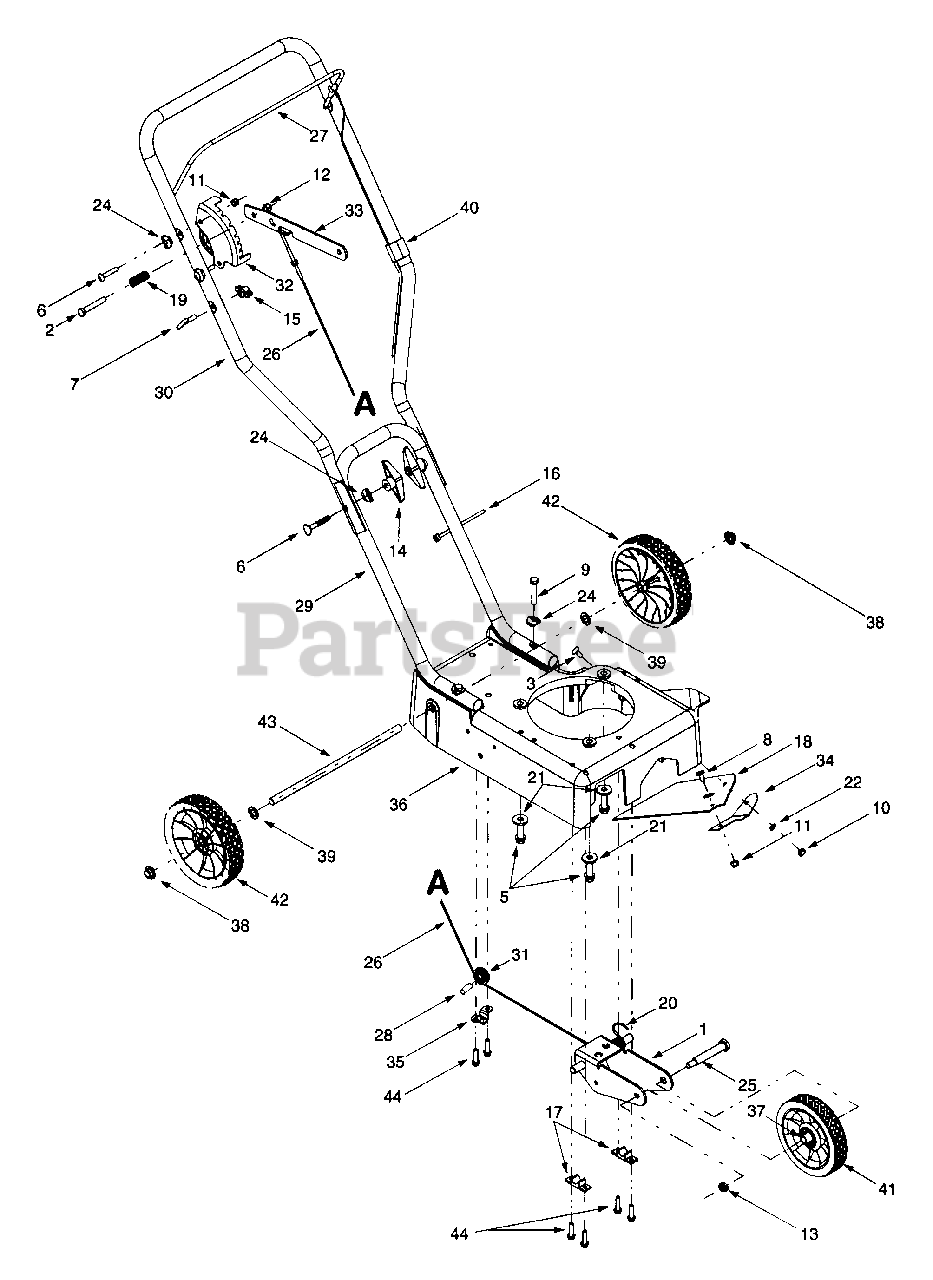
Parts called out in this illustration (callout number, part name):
1	Front Wheel Bracket Assembly
2	Hex Cap Screw, 5/16-18 x 2.0
3	Carriage Screw, 1/4-20 x.625
5	Sems Screw, 3/8-16 x 1.5
6	Carriage Bolt, 5/16-18 x 2.0
7	Eye Bolt (Rope Guide), 1/4-20
8	Hex Cap Screw, 1/4-20 x .5
9	Hex Cap Screw, 5/16-18 x 1.75
10	Hex Nut, 1/4-20
11	Hex Lock Nut, 1/4-20
12	Hex Lock Nut, 5/16-18
13	Jam Lock Nut, 3/8-16
14	Wing Knob, 5/16-18
15	Wing Knob, 1/4-20
16	Cable Tie
17	Block Bushing, .515 x .62
18	Discharge Deflector Shield
19	Compression Spring, .55 x 1.37
20	LH Torsion Spring, .655
21	Flat Washer, .385 x 1.0 x .135
22	Lock Washer, 1/4
24	Saddle Washer, .320 x .93
25	Shoulder Screw, 3/8-16, .5 x 2.62
26	Depth Index Cable, 44.5"
28	Cable Roller Rod
32	Depth Index Bracket
34	Discharge Deflector Keeper
37	Sleeve Spacer, .520 x .660
38	Push Cap, 1/2
39	Flat Washer, .5 x .875 x .606
40	Control Cable w/ Clip, 31.75"
41	Diamond Tread Wheel, 7 x 1.5
42	Diamond Tread Wheel, 8 x 1.5
43	Axle, 12.64
44	Hi-Lo Tap Screw, 1/4-15 x 1.0
